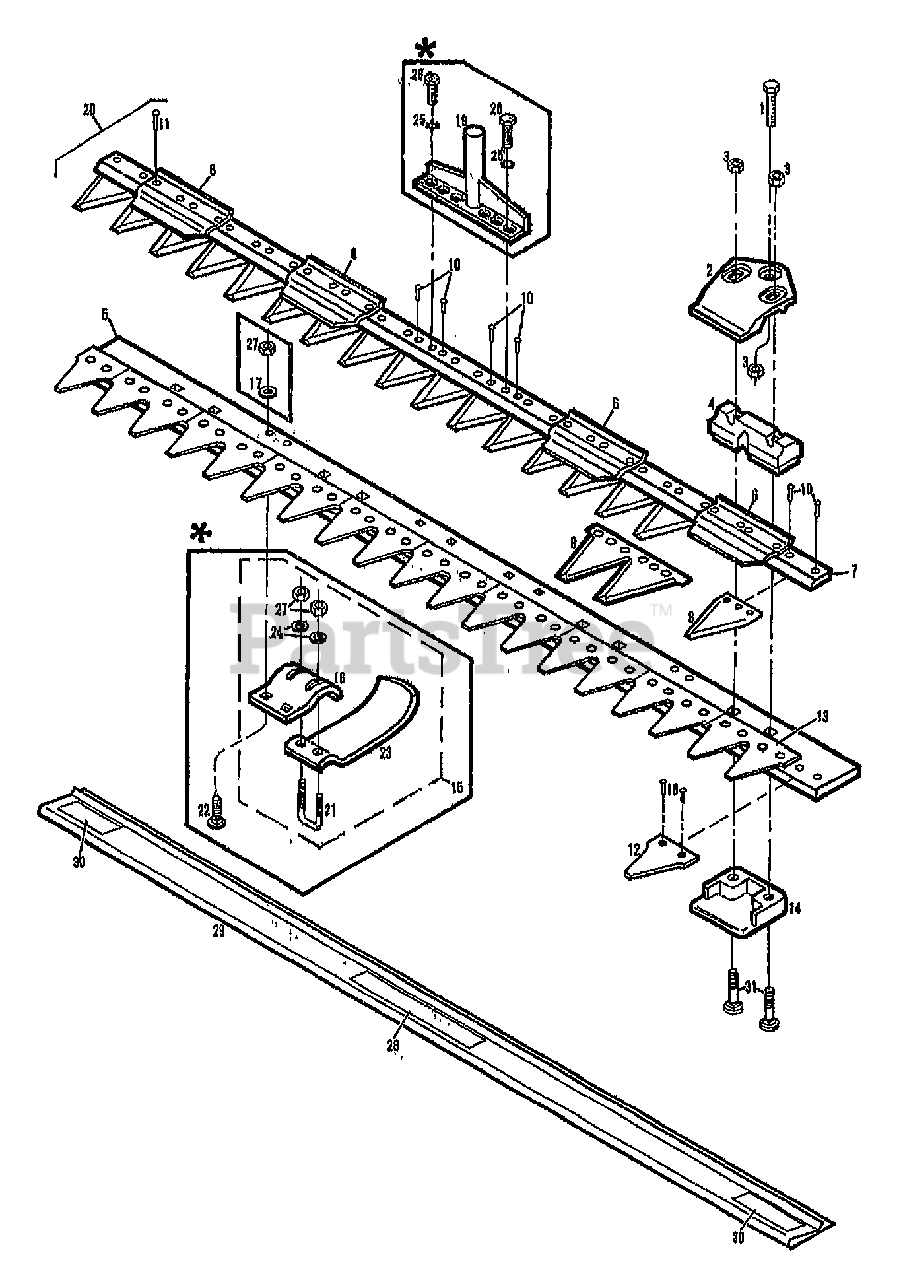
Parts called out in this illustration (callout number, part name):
1	SCR-HHC M8-1.25X30
2	CLIP-HOLD DOWN
3	NUT-H/LK M8
4	GUIDE-KNIFE
5	KNIFE-BACK BAR 34"
5	BAR-BACK 38"
5	BAR-BACK 42"
6	PLATE-WEAR
7	BAR-KNIFE 34"
7	BAR-KNIFE 38"
7	BAR-KNIFE 42"
8	KNIFE SECTION SINGLE
9	KNIFE SECTION (DOUBLE) 34"
9	KNIFE SECTION (DOUBLE) 38"
9	KNIFE SECTION (DOUBLE) 42"
10	KIT-RIVET 5X17 12 PKG
11	KIT-RIVET 5X20 12 PKG
12	PLATE-LEDGER SINGLE
13	PLATE-LEDGER DOUBLE
15	ASSM-SKID 2PC SET W/HDW (INCL. 16,21-24 & 27)
16	SHOE-SPUR HOLDER PNT
17	WASHER-FLAT M8
18	KIT-RIVET/SEC 6X20=12 PER
19	KIT-KNIFE HEAD & PITMAN
20	ASSM-34" BLADE T/B SICKLEBAR (INCL. 6-11)
20	KNIFE 38" (INCL. 6-11)
20	ASSM-42" KNIFE T/B SICKLEBAR (INCL. 6-11)
21	BOLT-U 5/16"-18
22	SCR-CARR 5/16-18X1.25 G2ZP
23	SHOE-PNT
24	WASHER-FLAT 5/16 SAE
25	WASHER-LK .312 INT TOOTH
26	SCR-HH M8
27	NUT-H/LK 5/16-18
28	DECAL-DANGER
29	COVER-BLADE
29	GUARD-BLADE 38"
29	GUARD-BLADE 42"
30	DECAL-ESM
31	SCR-HH M8X45
32	KIT-BLADE MAINT T/B SKLBR
